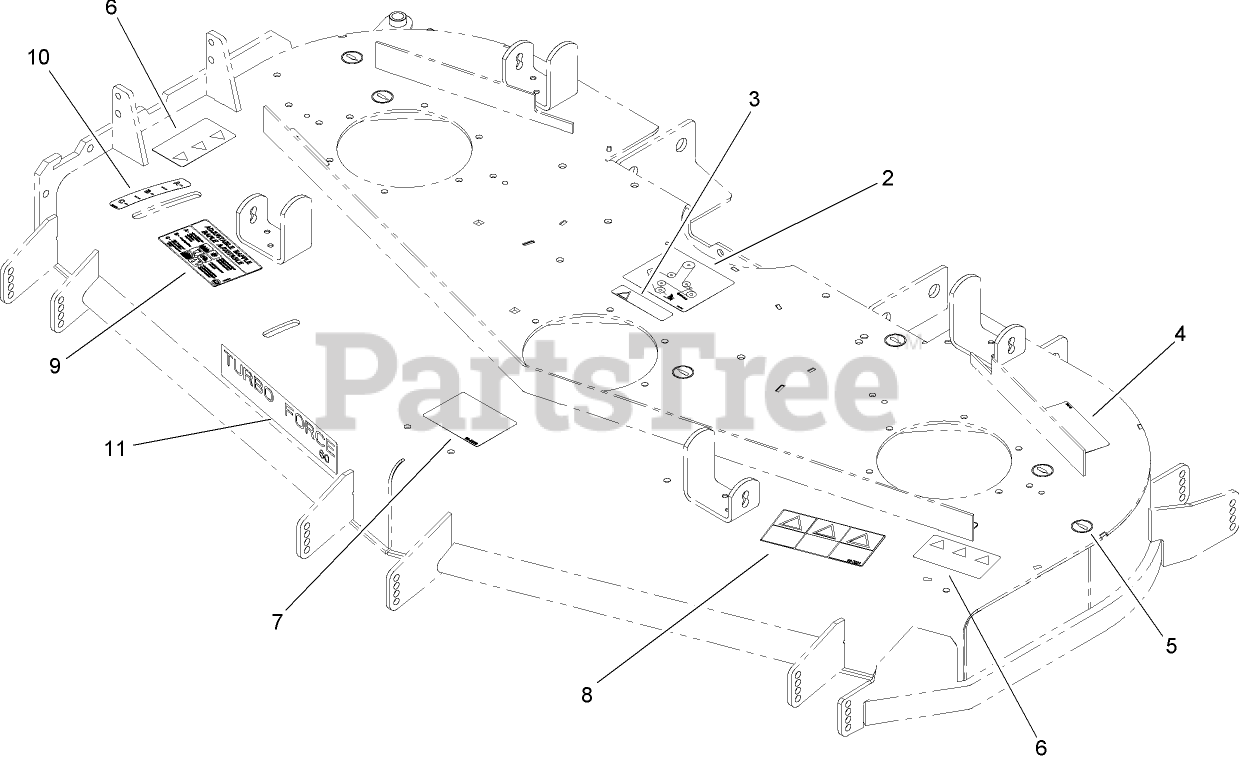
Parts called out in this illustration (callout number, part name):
2	DECAL-ROUTING, BELT
3	DECAL-WARNING
4	DECAL-TORQUE, BLADE BOLT
5	DECAL-GREASE
6	DECAL-DANGER
7	DECAL-ANTI SCALP
8	DECAL-DANGER
9	DECAL-ADJUSTMENT, BAFFLE
10	DECAL-SETTING, BAFFLE
